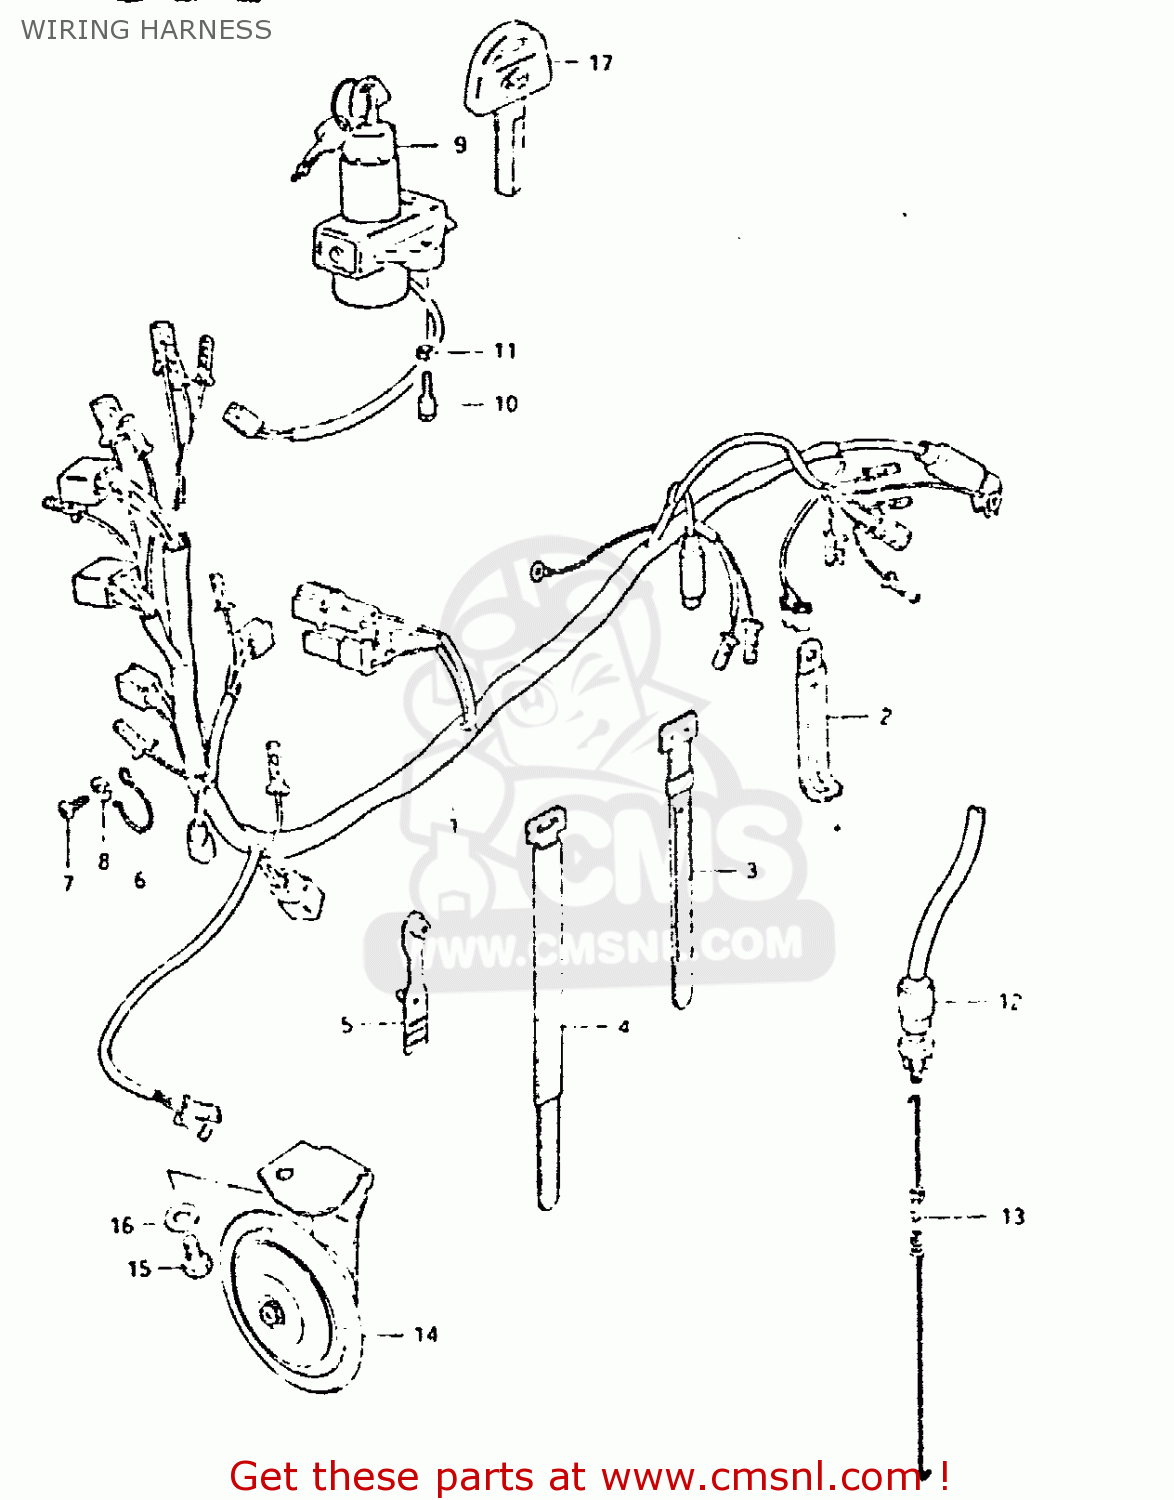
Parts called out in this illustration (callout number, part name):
1	WIRING HARNESS
2	CLAMP
3	CLAMP
4	CLAMP
5	CLAMP,L:88
6	GUIDE,WIRING HARNESS
7	SCREW 6X12
8	WASHER
9	LOCK ASSEMBLY,STEERING
10	BOLT
11	LOCK WASHER
12	SWITCH ASSEMBLY,STOP LAMP
13	SPRING
14	HORN ASSEMBLY
15	BOLT 8X12
16	WASHER
17	KEY,BLANK
